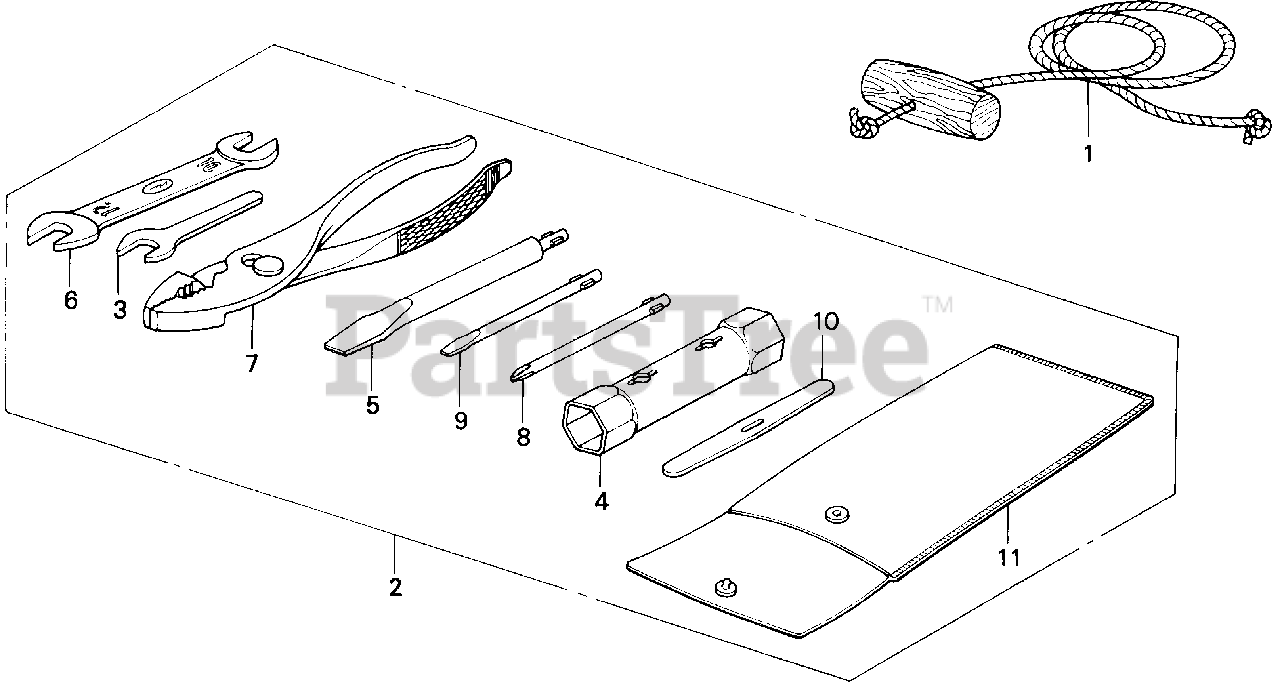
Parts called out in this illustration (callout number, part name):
1	ROPE, STARTER
2	TOOL KIT
3	WRENCH (8MM) (OPEN END) (NOT AVAILABLE)
4	WRENCH, BOX (P18X19) (NOT AVAILABLE)
5	SCREWDRIVER, CHECK BOLT
6	SPANNER (10X12)
7	PLIERS (135)
8	DRIVER 1, PLUS SCREW (NO.2)
9	DRIVER 3, MINUS SCREW (NO.2)
10	LEVER, TIRE
